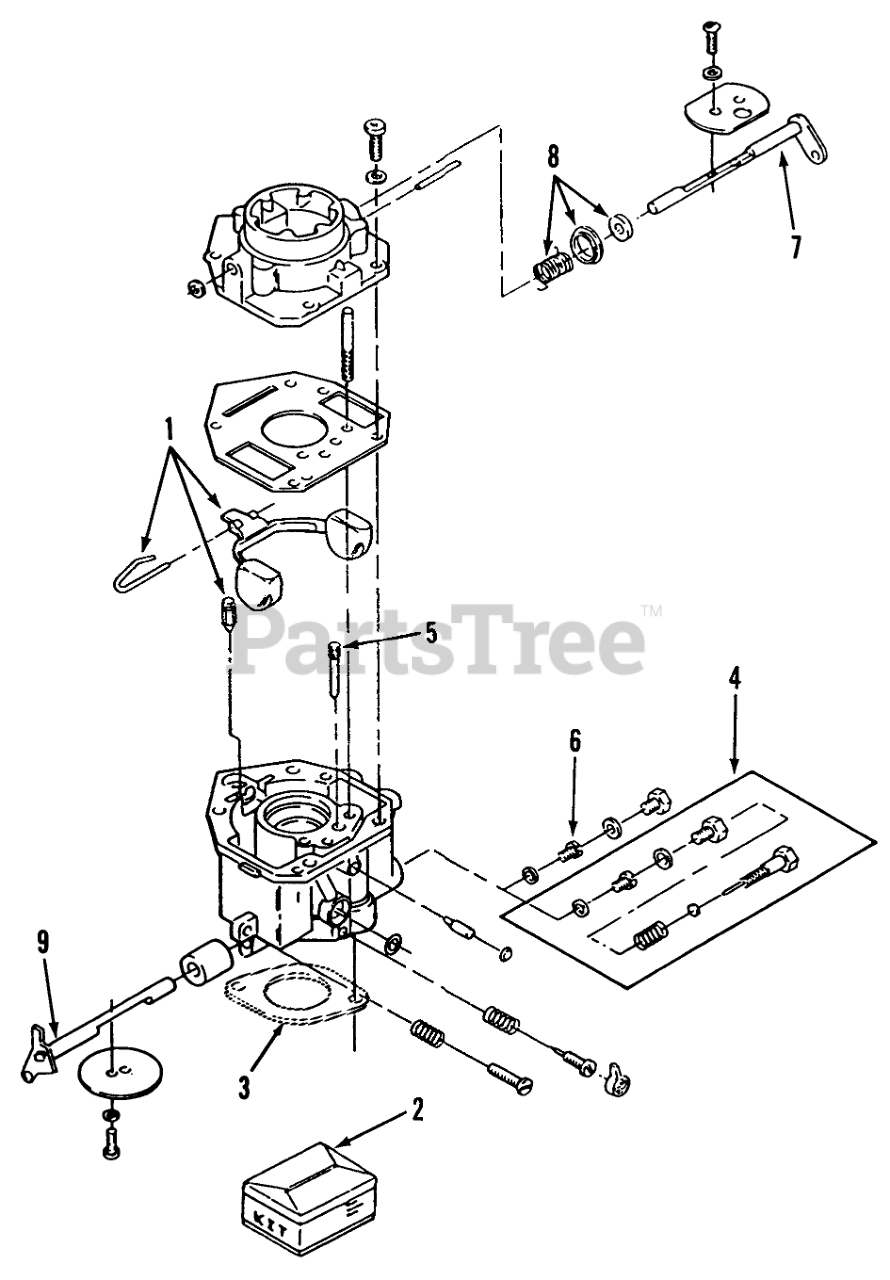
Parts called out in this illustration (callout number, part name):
1	Kit, Float (Includes Float, Pin and Valve)
2	Kit, Repair (Includes Screw and Plug Package, Gasket Package, Float Valve, Idle Adjust Needle and Spring, Mounting Gaskets, Idle Limit Cap)
3	Gasket
4	FIXED-JET
5	CRANK-SHAFT
6	POWER JET
7	Kit, Shaft-Choke (Includes Choke Valve, Valve Set Screw and Air Filter)
8	Kit, Lever-Choke (Includes Choke Lever Ring, Choke Spring and Choke Collar)
9	Kit, Shaft-Throttle (Includes Valve Set Screw, Air Filter and Throttle Valve)
11	SOLENOID - FUEL CUT OFF
